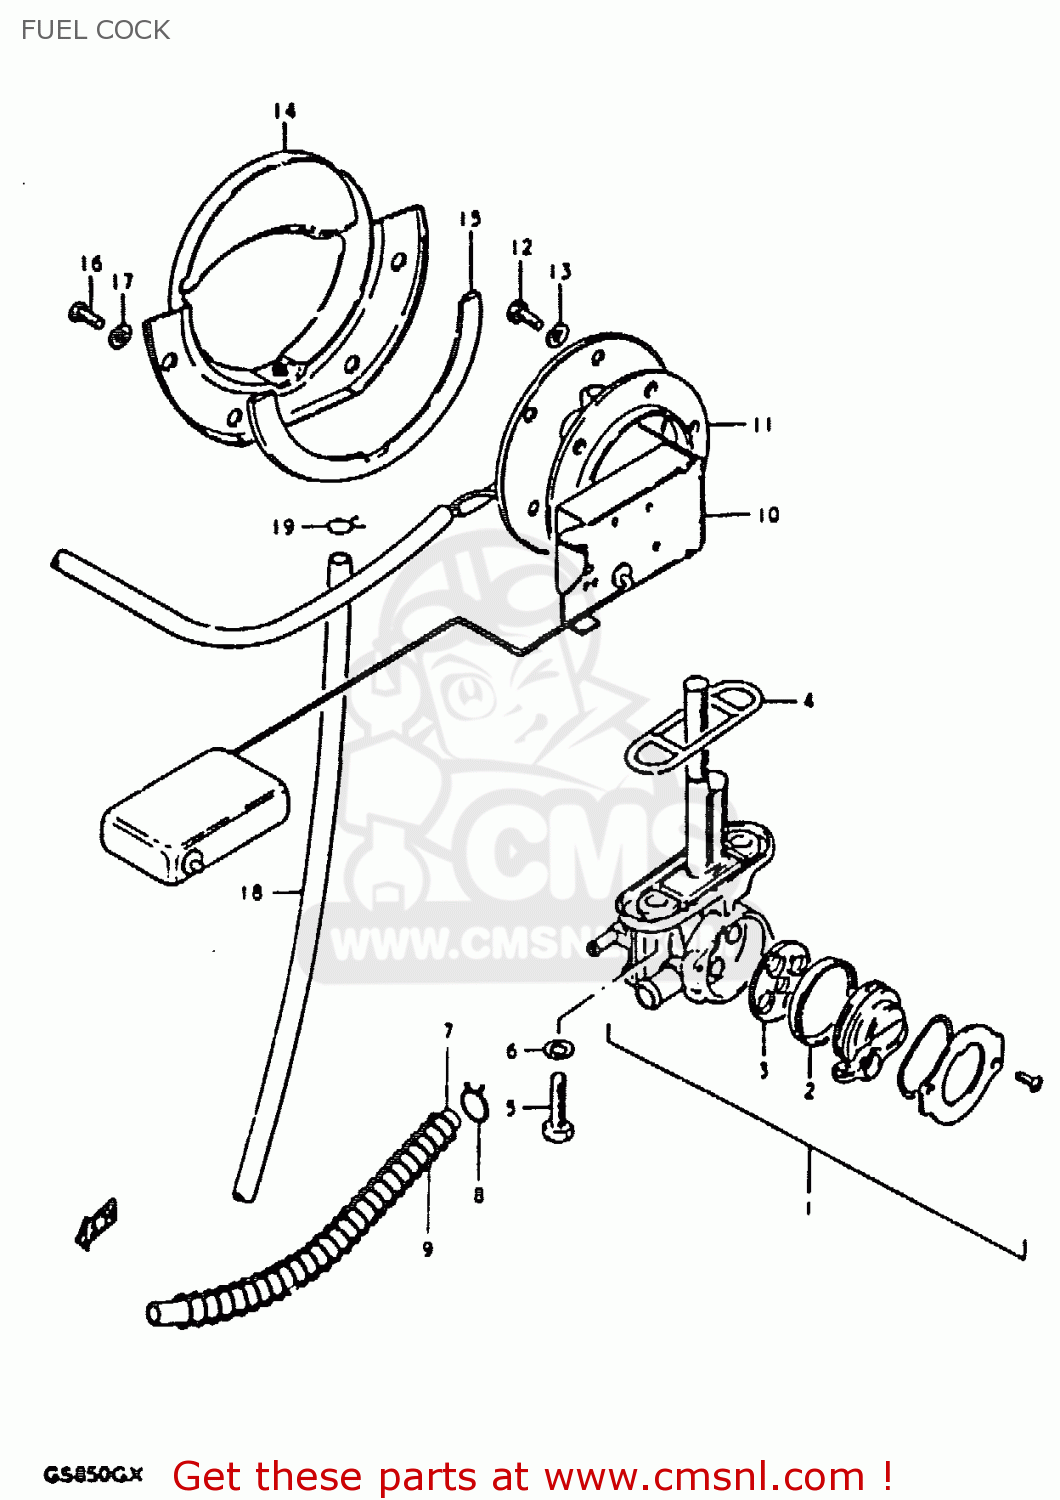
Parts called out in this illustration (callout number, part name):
1	COCK ASSY,FUEL
2	V SEAL,FUEL COCK
3	GASKET (NAS)
4	GASKET, FUEL COCK (NAS)
5	BOLT(6X20)
6	GASKET
7	HOSE
8	CLIP
9	SPRING
10	GAUGE ASSEMBLY,FUEL LEVEL
11	GASKET,FUEL LEVEL GAUGE (NAS)
12	BOLT
13	LOCK WASHER
14	PLATE,FUEL DRAIN
15	GASKET,FUEL DRAIN PLATE (NAS)
16	SCREW
17	LOCK WASHER
18	HOSE,FUEL
19	CLIP
